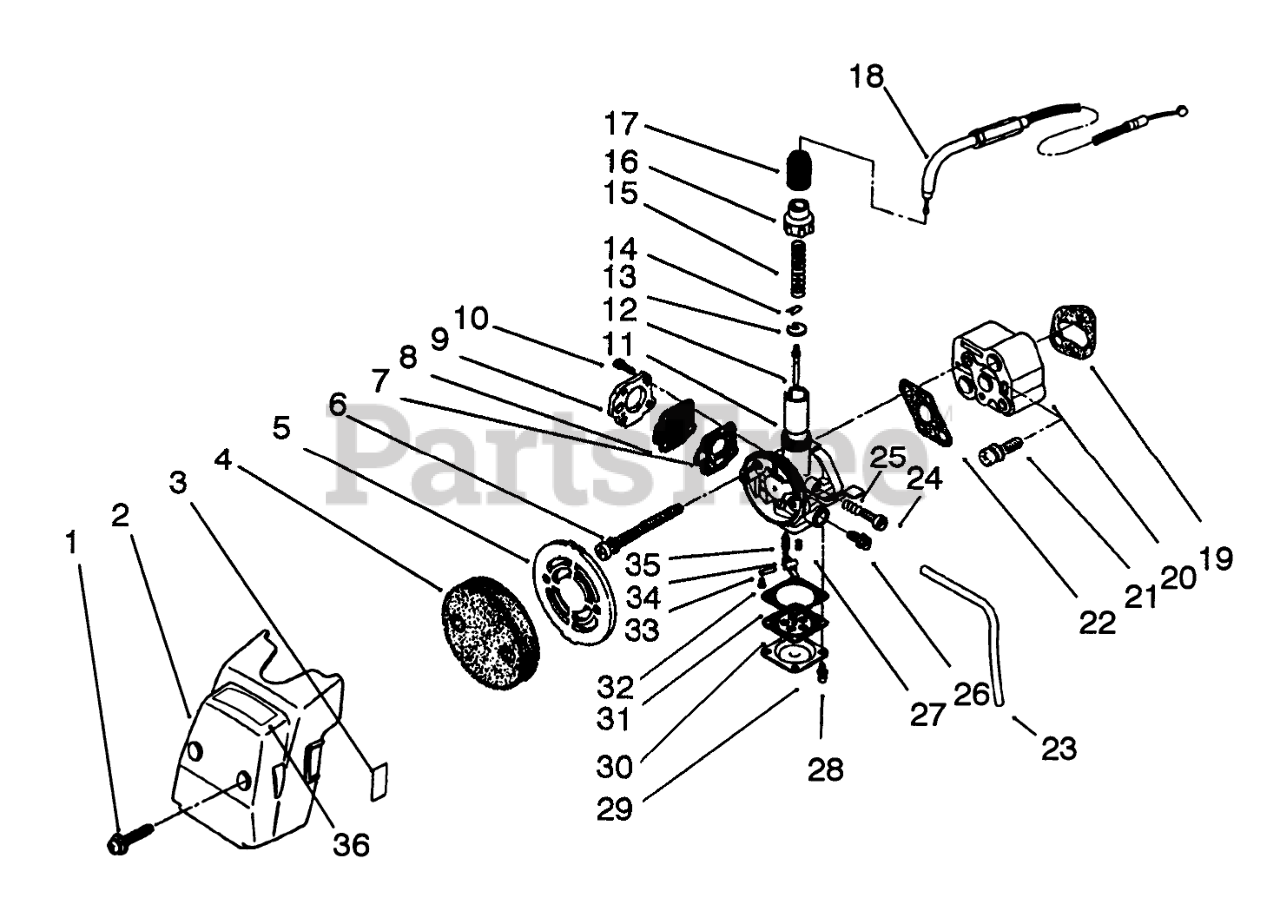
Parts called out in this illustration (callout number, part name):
1	SCREW & WASHER
2	CLEANER CASE
3	CHOKE LABEL
4	ELEMENT
6	SCREW W/ WASHER
7	PUMP COVER GASKET
8	PUMP DIAPHRAGM
9	Pump Cover Assembly
10	SCREW W/ WASHER
11	THROTTLE VALVE
12	NEEDLE JET
13	SPRING RETAINER
14	NEEDLE CUP
15	SPRING
17	AIR SEAL
18	WIRE, THROTTLE
19	INSULATOR GASKET
20	INSULATOR
21	SCREW & WASHER
22	CARB GASKET
23	FUEL TUBE
24	Screw-Adjusting
25	ADJ. SCREW SPRING
26	MAIN NEEDLE
27	VALVE SPRING
28	SCREW W/ WASHER
29	DIAPHRAGM COVER
30	MAIN DIAPHRAGM
31	DIAPHRAGM GASKET
32	FLOAT SCREW
33	FLOAT PIN
34	FLOAT ARM
35	FLOAT VALVE
36	Decal-Fuel Mix
